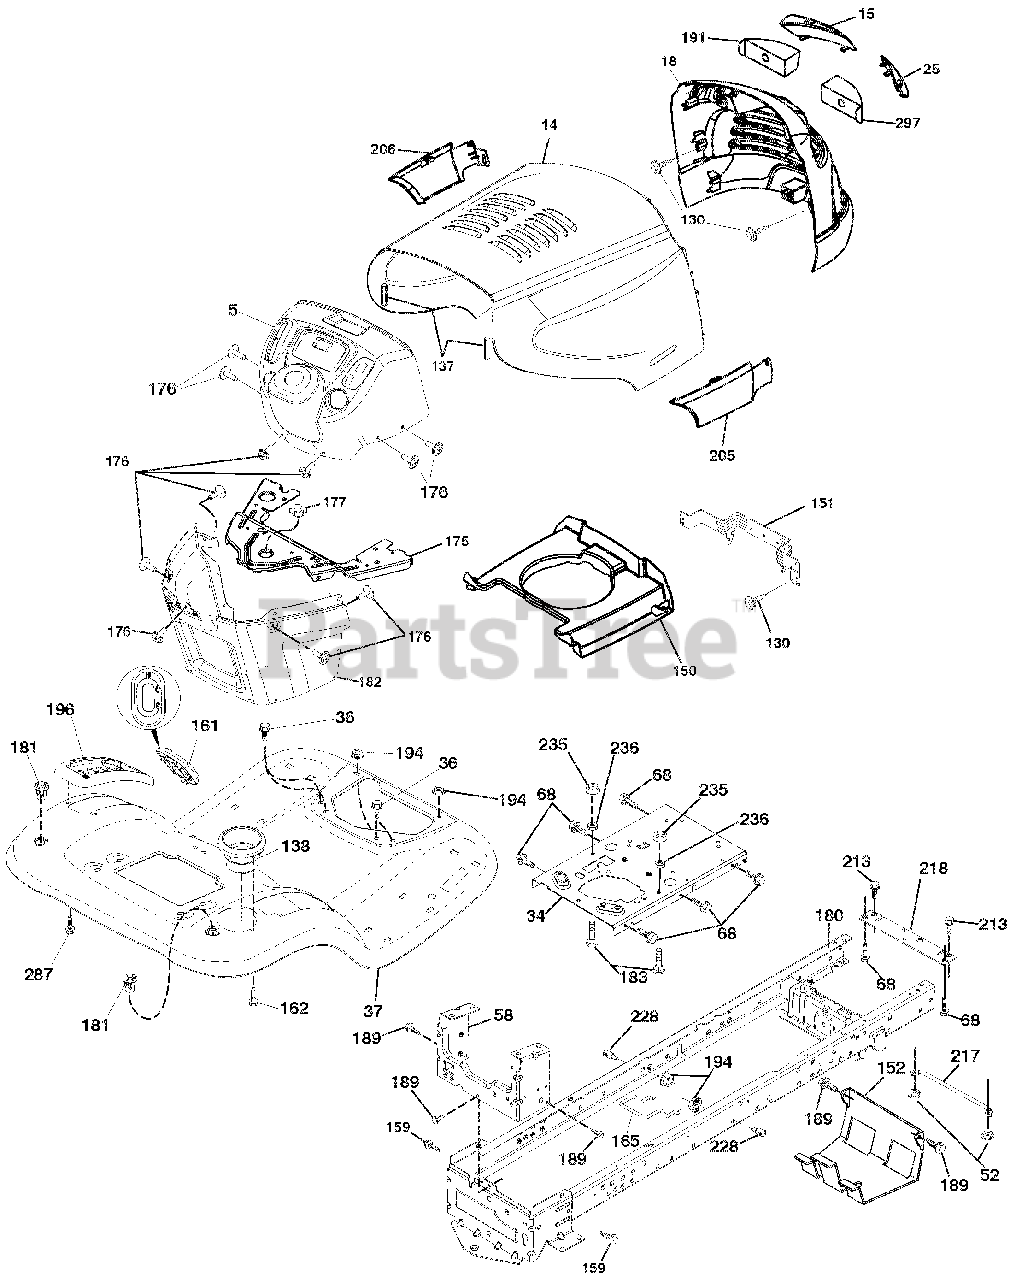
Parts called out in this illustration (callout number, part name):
5	DASH.UPPER.TEX.ELTE.CC.NCHK428
15	LENS.ELITE-HUSQ.CLEAR.LH
18	GRILLE ASM.ELITE.DL.ARIENS.BLK
25	LENS.ELITE-HUSQ.CLEAR.RH
34	PLATE.ENGINE.WELDED.CHASSIS
36	SCREW.5/16-18X3/4.SMGML.TAP/R
37	FENDER.TLT.W/CPH.W/FW.422
52	Nut, Hex, Crownlock 5/16-18
58	DRAWBAR.UPPER.2PC.SML.FENDER
68	SCREW.THDROL.5/16-18 X 1/2TYTT
137	BUMPER.HOOD.LARGE. 1.75"
138	CUPHOLDER.TL.TEX.428
150	AIR DUCT.ENGINE.ELITE-SV
151	BRACKET.PIVOT.LASR/ELTE/HUSQLT
152	SHIELD.BROWNING.W/TEX
159	SCREW.HEXWSH THDR3/8-16X3/4.BL
161	WINDOW.FUEL.LT.TEX.428
162	SCREW.HEX.WSH.HI-LO.1/4X1/2UNC
165	SUPPORT.TANK.REAR.W/TEX
175	CROSSMEMBER.LT
176	SCREW.#10-24X5/8.RND.QUDRX.GIM
177	BUSHING.STEERING.YT/GT
180	CHASS.WLDMT.TL.12GA/2PC.18/22"
181	BUSHING.MNT.FEND.CRGO.BLK.TEX
182	DASH LOWER.LT.CCS
183	BOLT.FIN.HEX.5/16-18UNC X1-1/4
189	SCREW.5/16-18X3/4.SMGML.TAP/BL
191	INSERT.LENS.RFLCT.ELT-HUSQ.
194	Nut, Lock Hex Flange 5/16-18 u
196	CONSOLE ASM.DECKLFT.BL/RBT.TLT
205	SKIRT.SIDE.RH.ELITE HUSQ.428
206	SKIRT.SIDE.LH.ELITE HUSQ.428
213	Bolt, Hex Head 5/16-18 x 3/4
217	ROD.PIVOT.HOOD
218	X-PIECE.HOOD.STOP.NON/STEALTH
228	STUD.FASTNER.W/'D'ANTI-ROTATIO
235	SPACER.FENDER
236	NUT.CENTER LOCK.5/16-18 UNC
287	SCREW.HEX.WASHEAD.1/4-20 X 3/8
297	INSERT.REFLECTIVE.RH.
